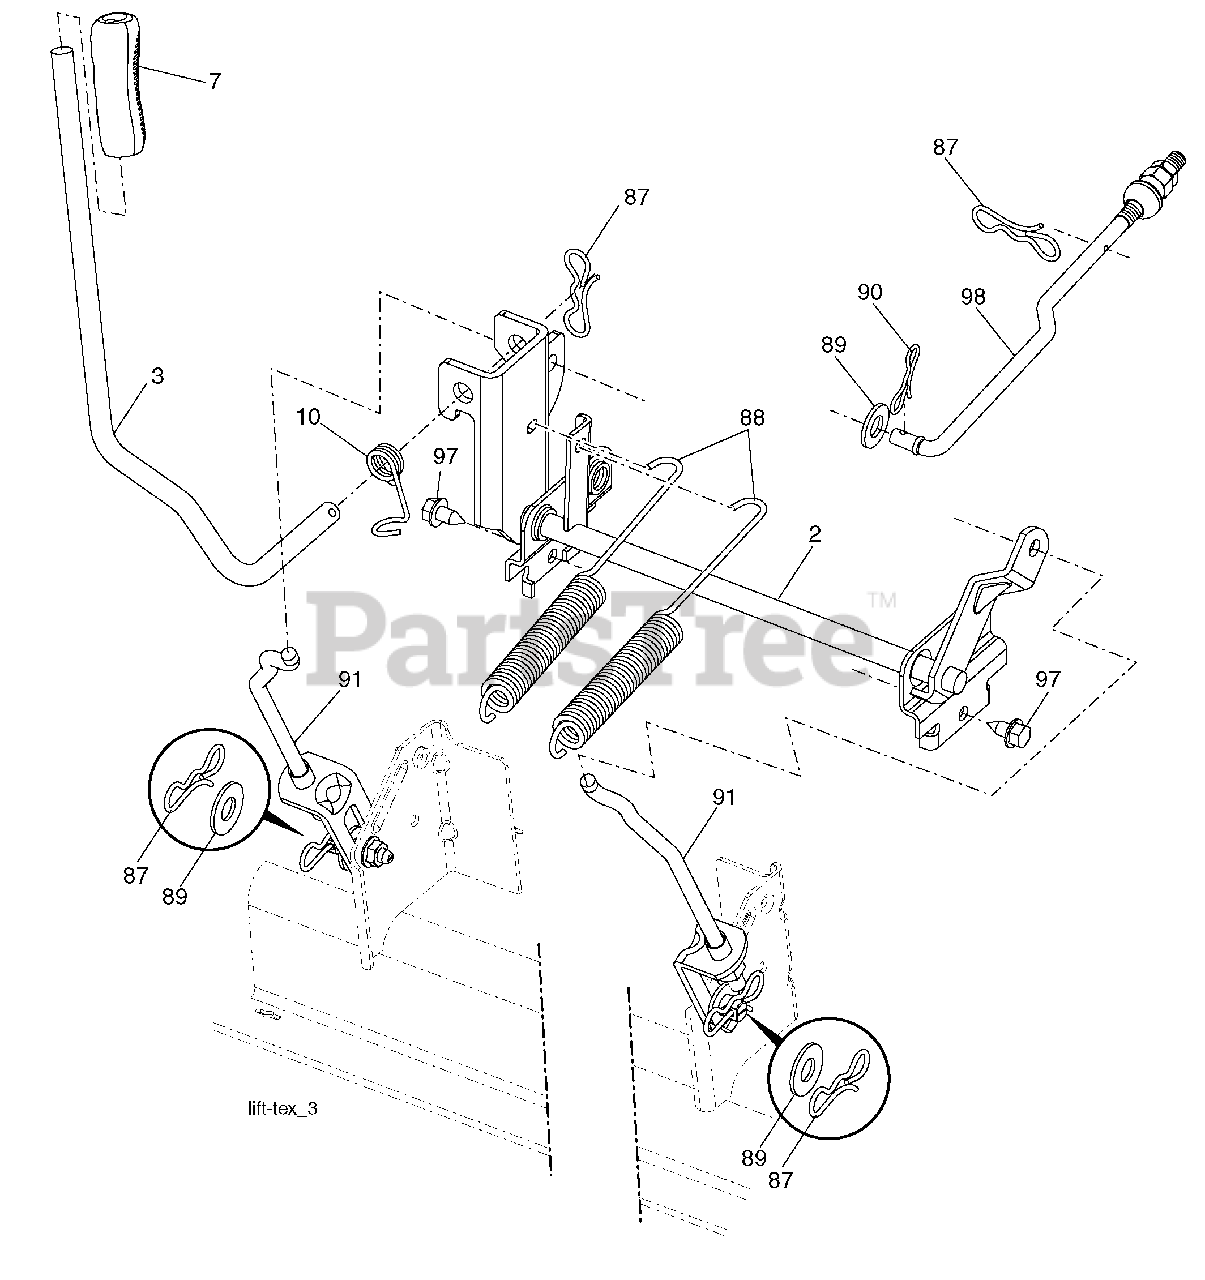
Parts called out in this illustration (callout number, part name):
2	Shaft Asm. Cross, Lift
3	Lever Asm., Lift
7	Grip, Lever
10	Spring Torsion
87	Pin Cotter 7/16 Bow Tie Lock
88	Spring Lift Assist
89	Washer Clear Zinc
90	Pin Cotter 5/16 Bow Tie Lock
91	Link Lift Susp Mower Rear
97	Screw 3/8-16 x .75
98	Link Lift Susp. Front Mower
